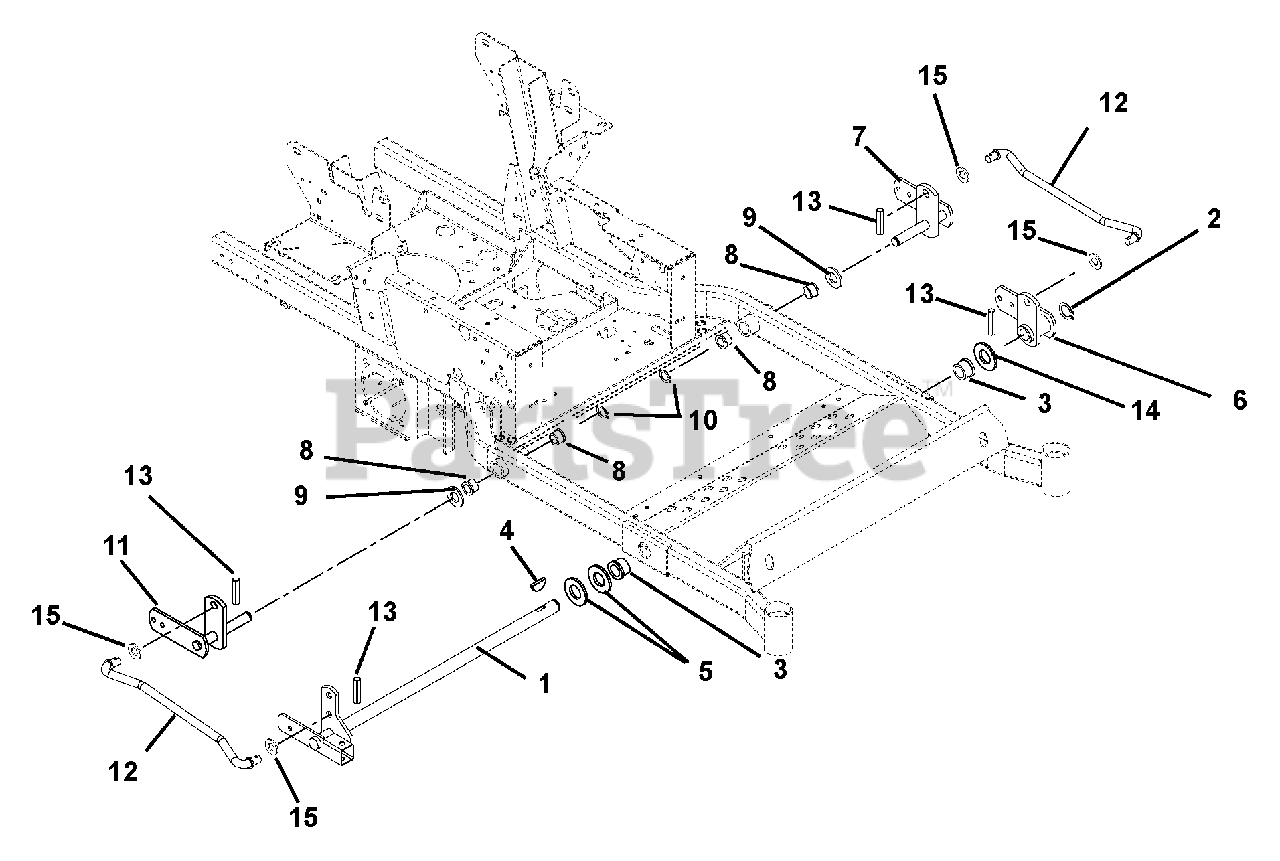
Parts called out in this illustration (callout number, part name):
1	MOWER LIFT
2	RG-RTNG-EXT 1.00X.078
3	BSHG-FLG1.020X1.385X.75X1.75NY
4	KEY-WDRF .25X1.00 HRD #15
5	WSHR-FL-STL- 1.062X2.0X.134 YZ
6	WMT, FRONT MOWER LIFT-LH
7	WMT, REAR LIFT ARM -LH
8	BSHG-FLG .762X1.0X.580X1.48 NY
9	WSHR-HDND-THRST .758X1.23X.031
10	RG-RTNG-EXT .689X.078
11	WMT, REAR LIFT ARM - RH
12	ROD, LIFT ASSIST 16.35"
13	PIN-ROLL .250X1.25 STNLESS STL
14	WSHR-HDND-THRUST 1.00X1.55X.03
15	WSHR-FL-STL .630X1.250X.062 YZ
